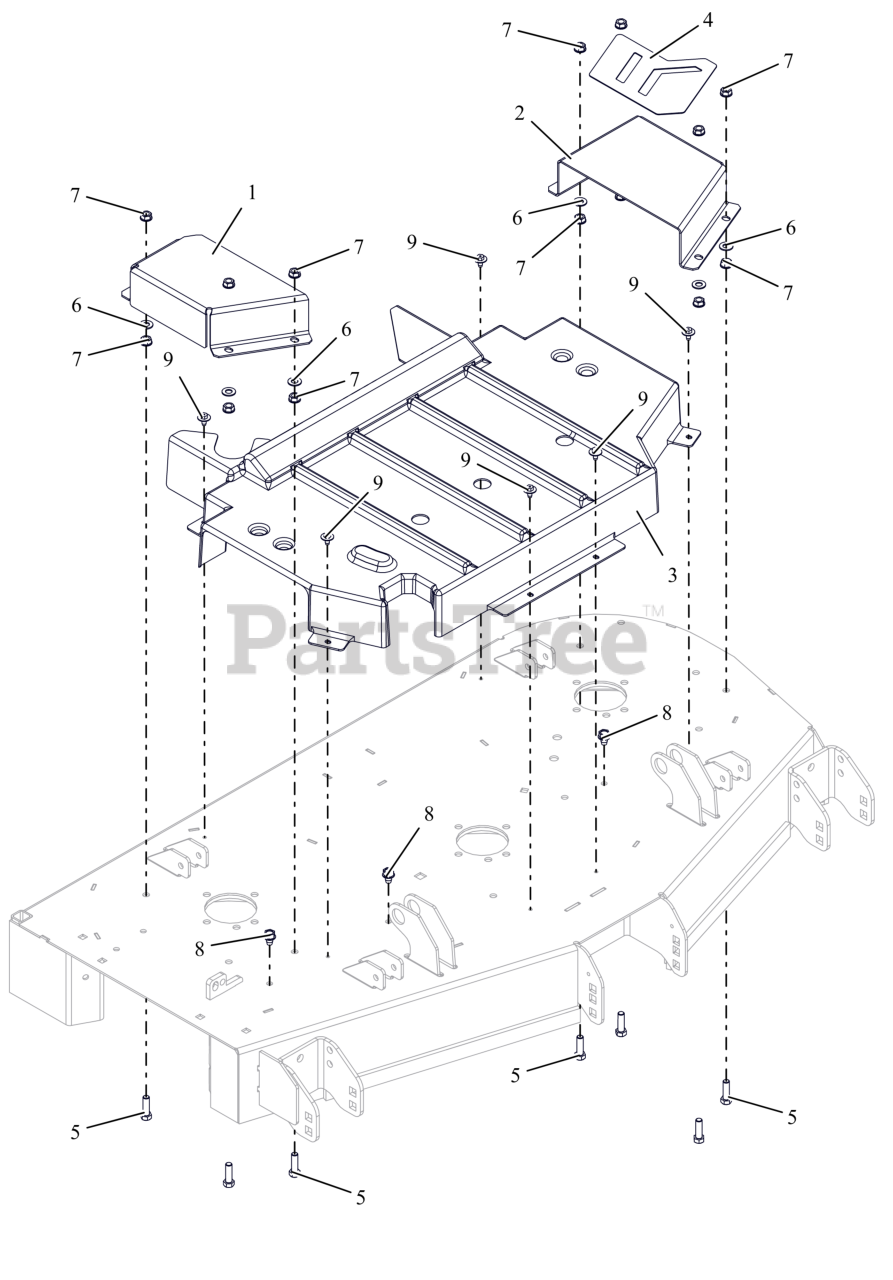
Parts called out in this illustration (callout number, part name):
1	GUARD, BELT 48" RIGHT CE (ORANGE)
2	GUARD, BELT 48" LEFT CE (ORANGE)
3	GUARD, CENTER DECK SPINDLE CE
4	GRIP TAPE 48 BELT COVER
5	BLT, HEX .38-16X1.25 G5 ZCC
6	WSHR,FLT .406X.812X.065 ZCC
7	NUT, SPNLK-FLG .38-16 G5 ZCC
8	SCR,TAP .375-16X.50 HWH TR ZCC
9	SCR, TAP .25-20X.50 LG HWH ZCC
